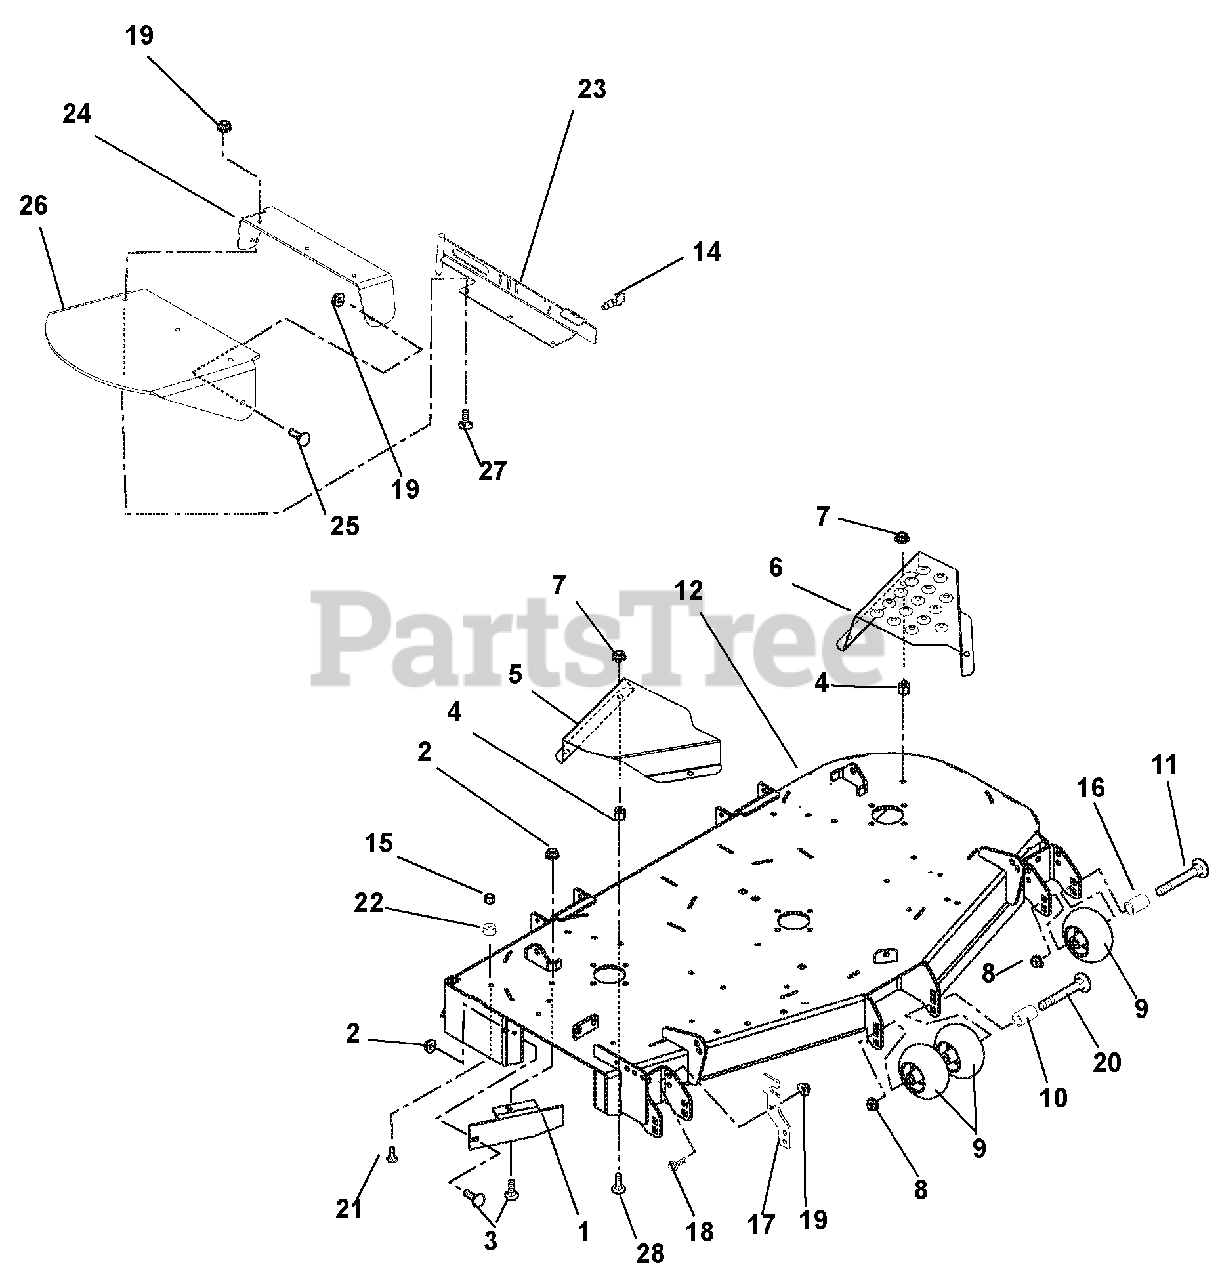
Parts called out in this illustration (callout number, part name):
1	60-in. Discharge Baffle
2	Nut, .31-18 Nyloc Flange
3	Bolt, Round Head Square Neck .31-18 x 1.00 Grade 5
4	Nut, Heavy Hex .38-16
5	60-in. Right Hand Spindle Guard
6	60-in. Left Hand Spindle Guard
7	Nut, Spin Lock Flange .375-16
8	Nut .50-13 Nyloc Flange
9	Anti-Scalp Wheel
11	Bolt, Round Head Square Neck .50-13X5.00
12	60-in. Mower Deck
13	Knob, Clamping, .312-18 Nyloc
14	Pin, Plunger Pull .50-13 Thread x .310 Diameter
15	Nut, Locking Center .31-18
16	Spacer, .510 x .625 x 3.35
17	Chute, Storage Bracket
18	Bolt, Hex .38-16 x 1.00 Grade 5
19	Nut, .38-16 Nyloc Flange
20	Bolt, Round Head Square Neck .50-13 x 8.50
21	Bolt, Round Head Square Neck .31-18 x 1.50
22	Bumper, Recessed 1.50 x .63 , .31 Thru Hole
23	52-inch and 60-inch Discharge Chute Mounting Weldment
24	Rubber Discharge Chute Support
25	Bolt, Round Head Square Neck .38-16 x 1.00 Grade 5
26	Chute, Rubber Discharge
27	Bolt, Round Head Square Neck .38-16 x 1.25 Grade 5
28	Bolt, Hex .38-16 x 1.25 Grade 5
